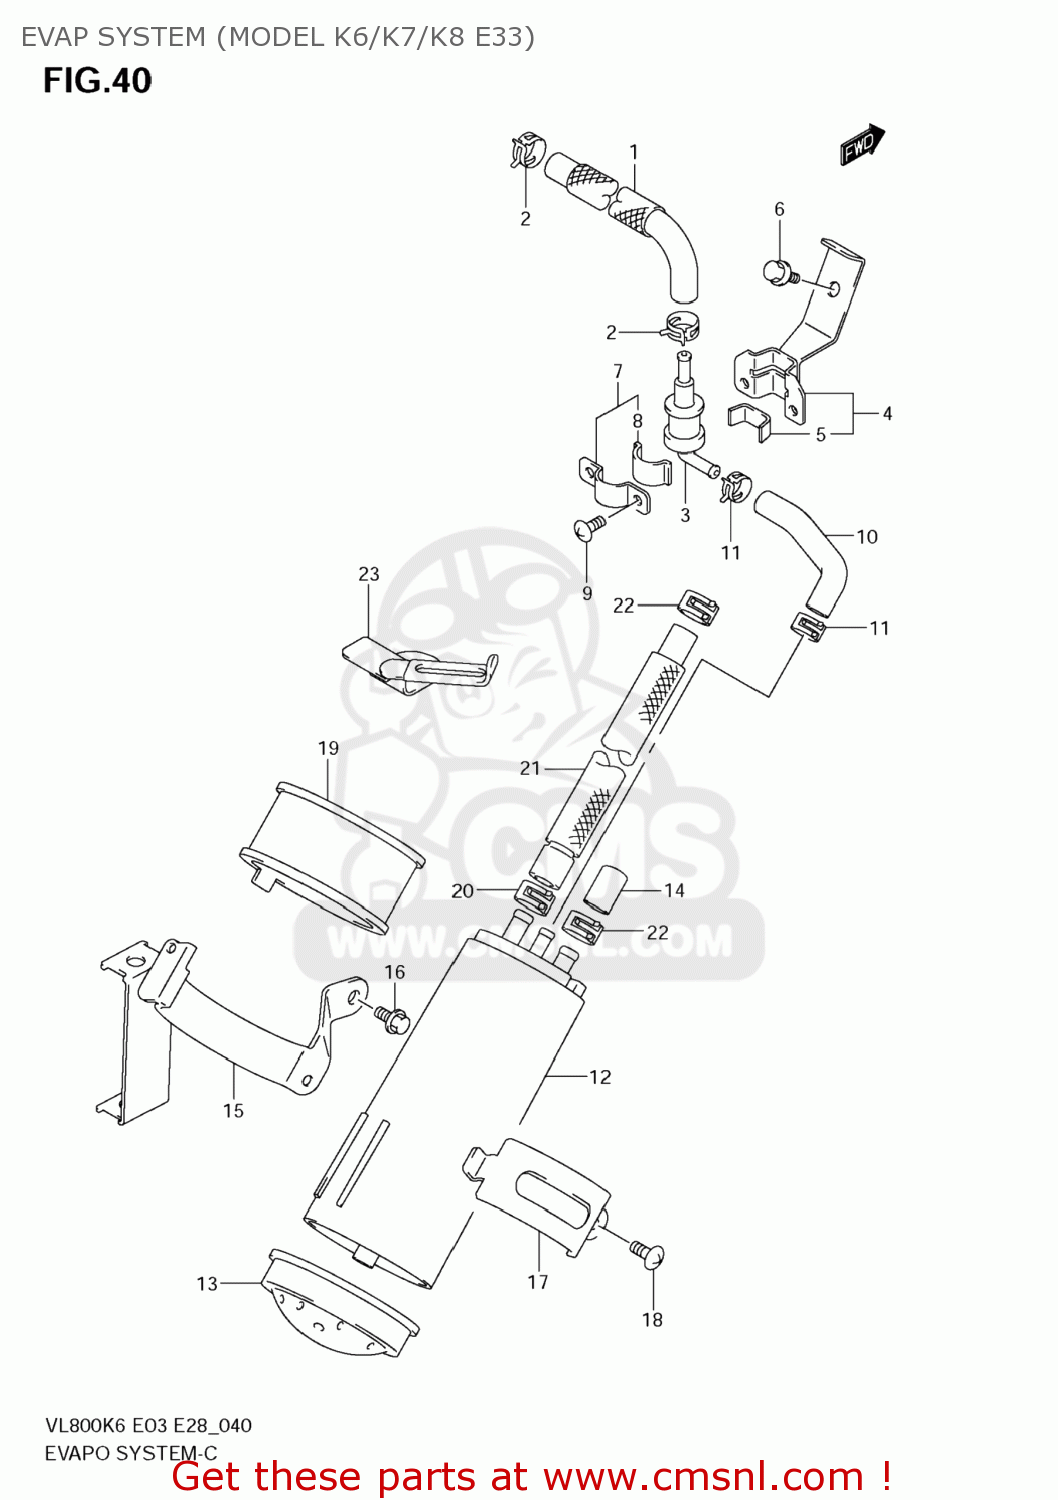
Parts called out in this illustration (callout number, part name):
1	HOSE,TANK & BRT
2	CLIP
3	VALVE,FUEL TANK BREATHER
4	BRACKET,FUEL TANK BREATHER
5	CUSHION
6	BOLT
7	PLATE,FUEL TANK BREATHER NO.2
8	CUSHION
9	SCREW
10	HOSE,BRTHR VALV
11	CLIP
12	CANISTER ASSY,CHARCOAL
13	CAP,CANISTER
14	CAP,OD:11.5
15	BRACKET,FI CONTROL UNIT
16	SCREW(6X12)
17	HOLDER,CANISTER
18	SCREW
19	CUSHION,CANISTER
20	CLIP
21	HOSE,CSTR PURGE
22	CLIP
23	CLAMP,EVAPORATOR HOSE
